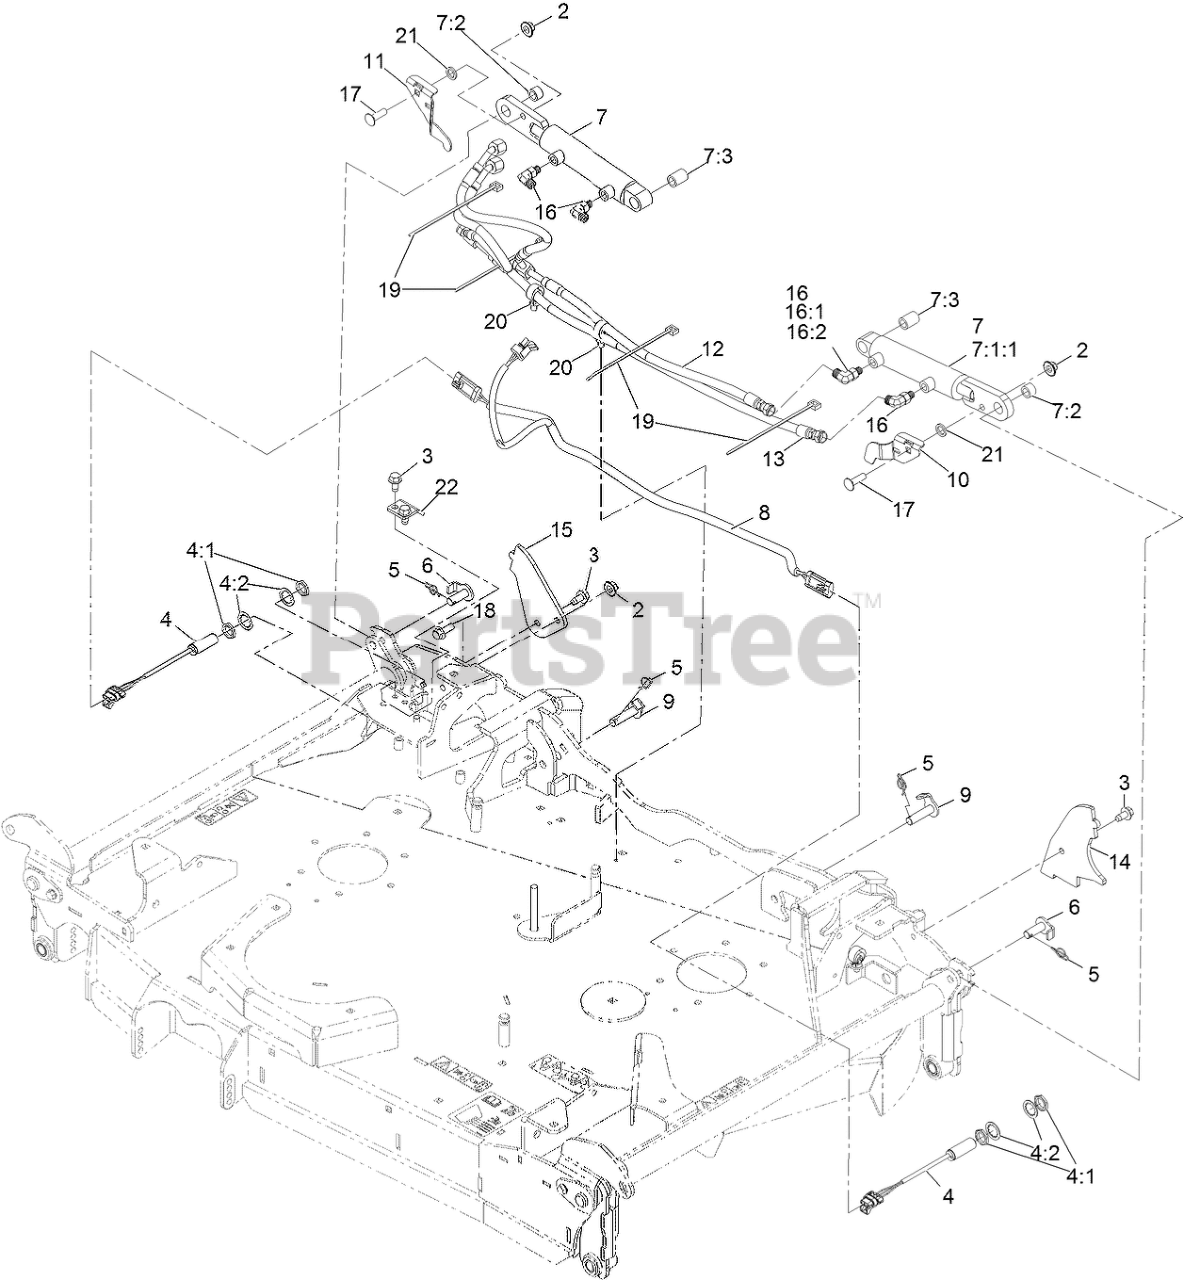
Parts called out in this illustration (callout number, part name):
2	Nut-Nyloc 3/8-16 Flg
3	SCREW-HWH
4	PROXIMITY SWITCH ASM
4:1	NUT-HEX
4:2	WASHER-LOCK, INTERNAL TOO
5	PIN-COTTER, LOCKING
6	EYE-PIN, CYLINDER
7	DECK FOLD CYLINDER ASM
7:2	BUSHING
7:3	BUSHING
8	HARNESS-WIRE
9	BASE-PIN, CYLINDER
10	Plate-Proximity, LH
11	Plate-Proximity, RH
12	HOSE ASM
13	HOSE ASM
14	BRACKET-DECK STOP, LH
15	BRACKET-DECK STOP, RH
16	FITTING-ELBOW, 90 DEG
16:1	O-RING
16:2	O-RING
17	Bolt-Carriage 3/8-16 X 1 1/4
18	SCREW-HHF 3/8-16 X 1
19	TIE-CABLE
20	CLIP-TIE
22	BRACKET-GUARD, SWITCH (RH)
